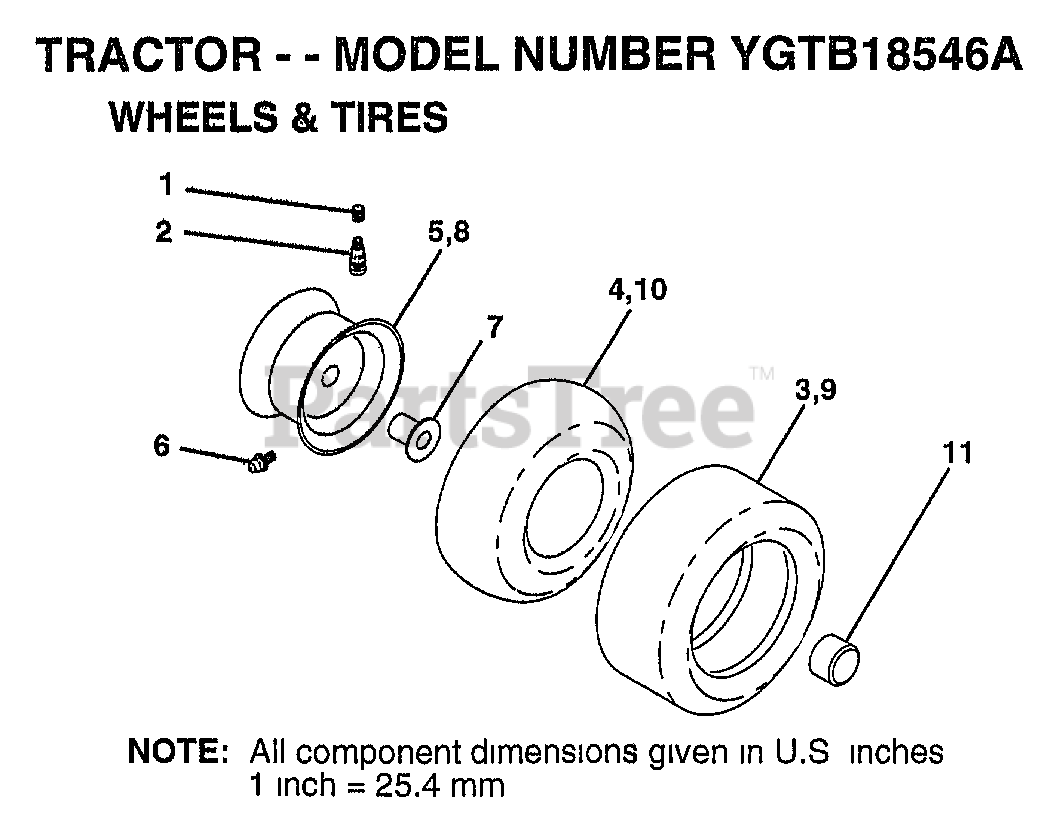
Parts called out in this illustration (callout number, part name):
1	VALVE CAP
2	VALVE STEM LT
5	"RIM ASM 8"" FRT"
6	FITTING LT
7	"FLANGE, BEARING"
8	RIM.REAR.
10	TUBE.23X8/10-12
11	HUB CAP
